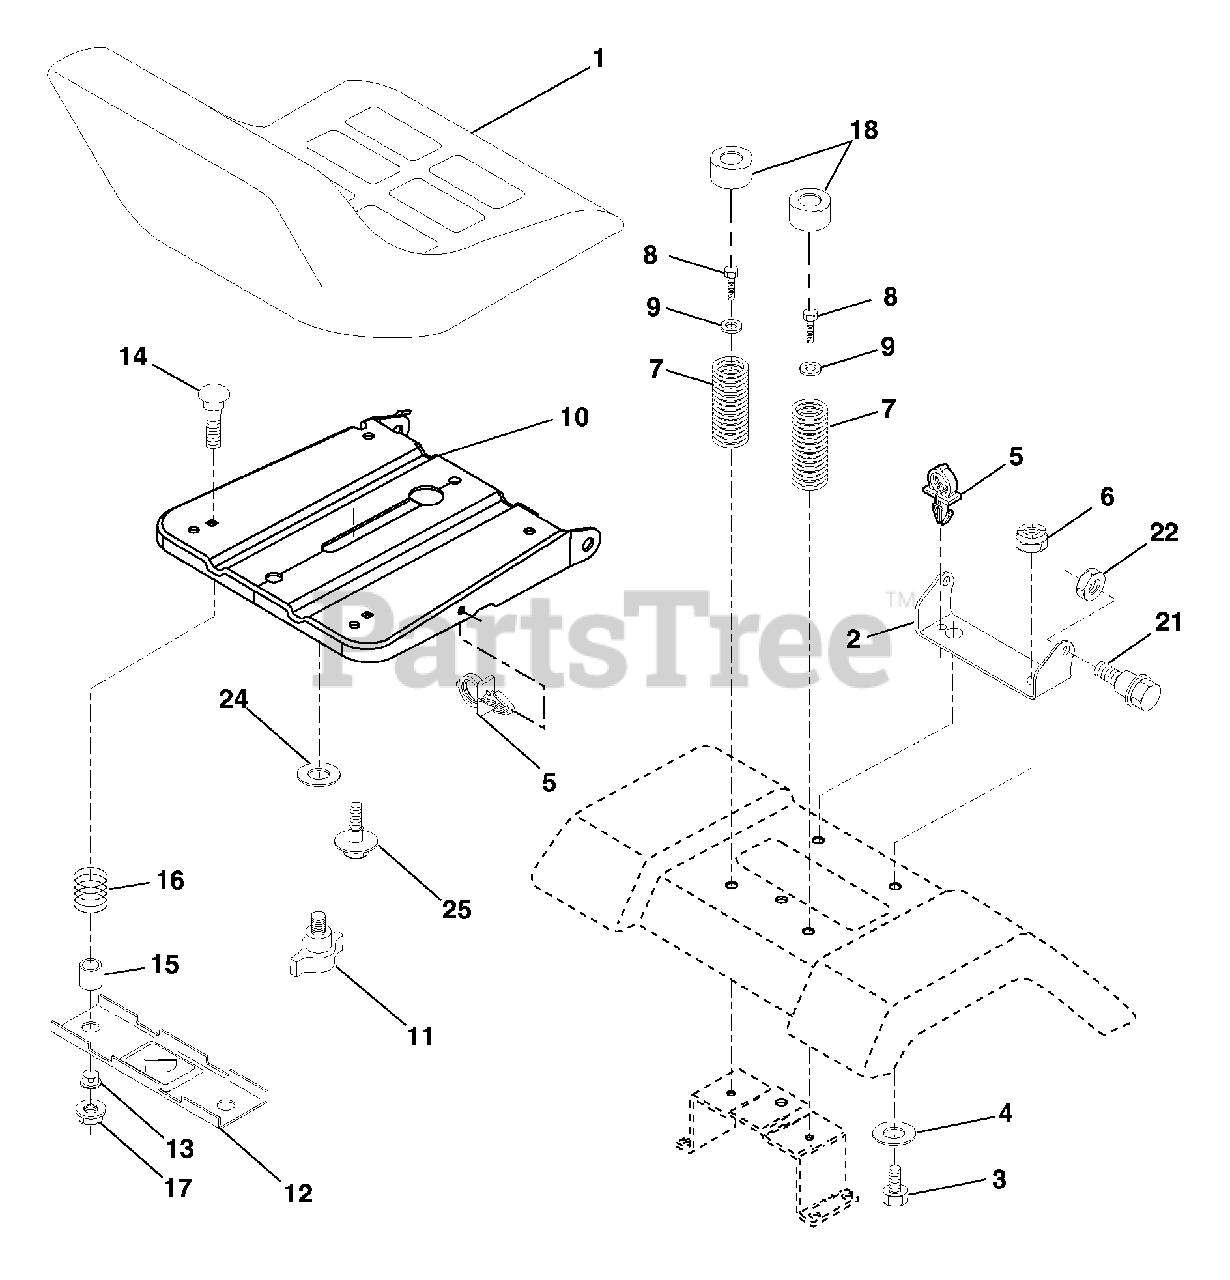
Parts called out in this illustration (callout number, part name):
1	Seat
2	Bracket Pivot Seat 8 720
3	Bolt Fin Hex 3/8-16 unc x 1
4	Washer 13/32 x 1 x 10 Ga.
5	Clip Push-In
6	Nut Hex w/Ins. 3/8-16 unc
7	Spring Seat Cprsn 2 250 Blk Zi
8	Screw 3/8-16 x 1.5 Smgml
9	Washer 13/32 x 1 x 14 Ga.
10	Pan Seat
11	Knob Seat
12	Bracket Mounting Switch
13	Bushing Snap Blk Nyl 50 Id
14	Bolt Rdhd Sqnk 1/4-20 x 1-1/2
15	Spacer Split 28x 88
16	Spring Cprsn
17	Nut Lock 1/4 Lge Flg Gr. 5 Zinc
18	Cap Spring
21	Bolt Shoulder 5/16-18 unc
22	Nut Hex Lock W/Ins 5/16-18
24	Washer 17/32 x 1-3/16 x 12 Ga.
25	Bolt Shoulder 5/16-18 x 62
